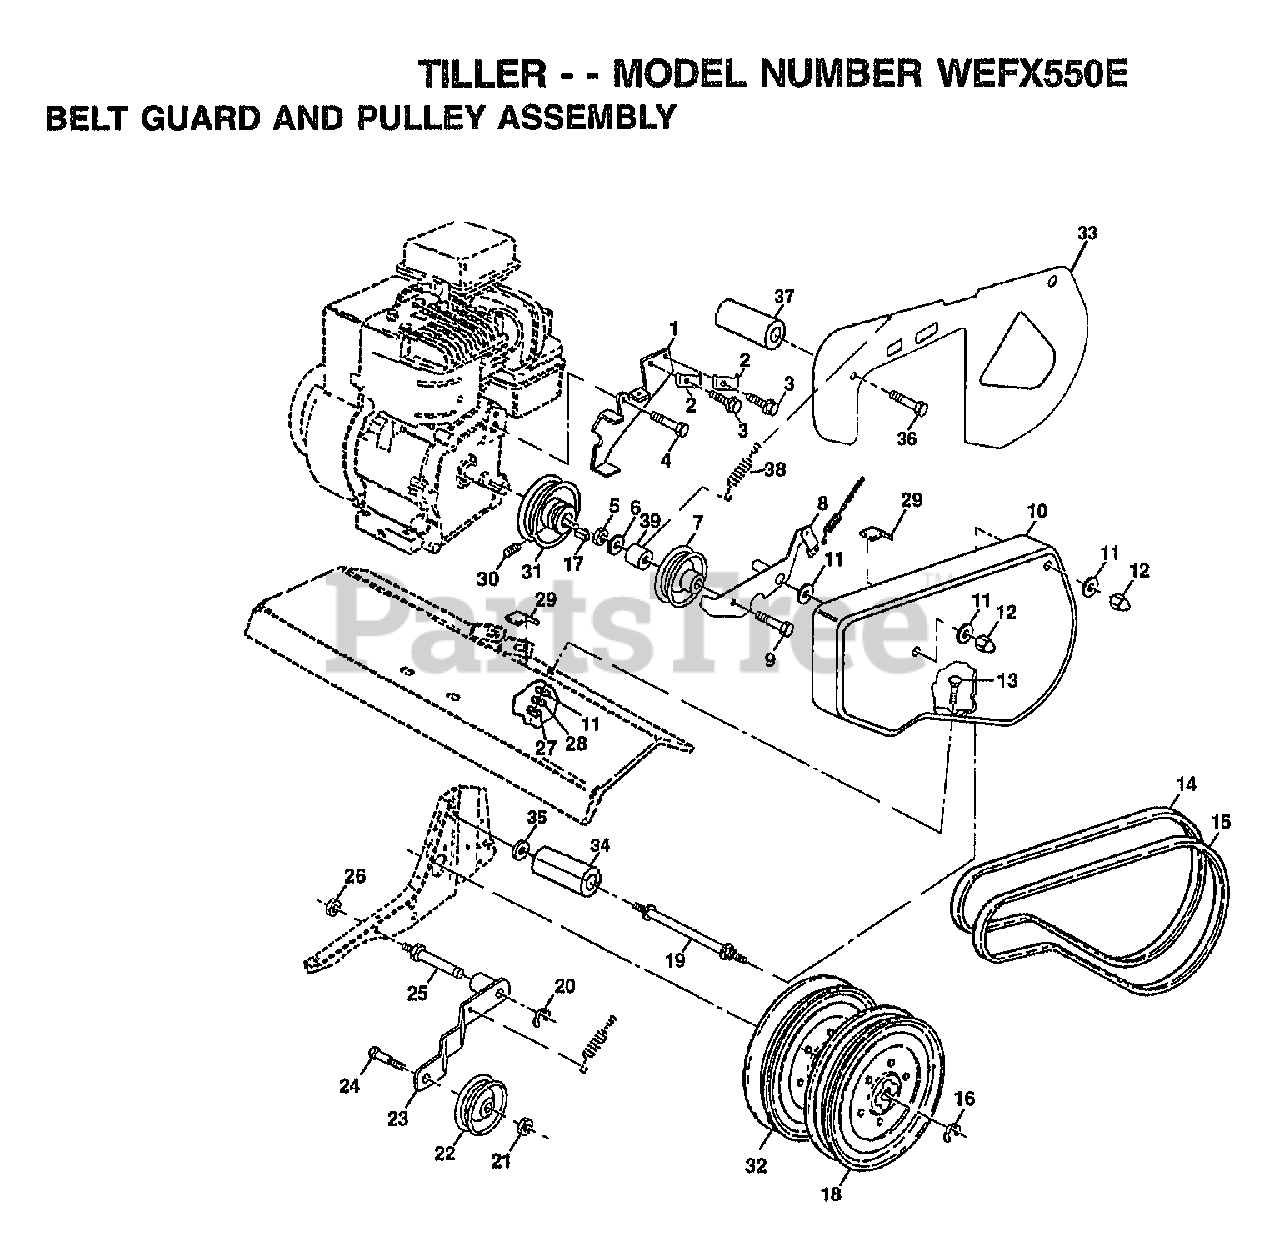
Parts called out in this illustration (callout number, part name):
1	ASSY.BRKT.BELT GUARD
2	CONDIUT CLIP T
4	BOLT.HEX.HEAD
5	NUTLOCK 3/8-16
6	WASHER
7	PULLEY W/SPACER
8	ASSY ARM REV.IDLR
10	"GUARD,BELT"
11	WASHER
12	NUT-CAP TI
13	BOLT T
14	BELT-V
17	KEY T
18	SHEAVE.TRANS
19	BOLT TI
20	KLIP RING TI
21	NUT
22	"PULLEY,IDLER"
23	"ARM, IDLER"
25	SHAFT IDLER TI
26	JAM NUT TI
28	LOCKWASHER
29	PAD IDLER TI
30	SET SCREW
31	ENGINE PULLEY TI
32	"SHEAVE,TRANS.""D"""
33	"SHIELD,BELT GUARD"
34	SPACER.SPLIT
35	WASHER
36	BOLT.5/16X24X1
37	SPACER.SPLIT
38	"SPRING,EXT"
39	SPACER.500X384X23
